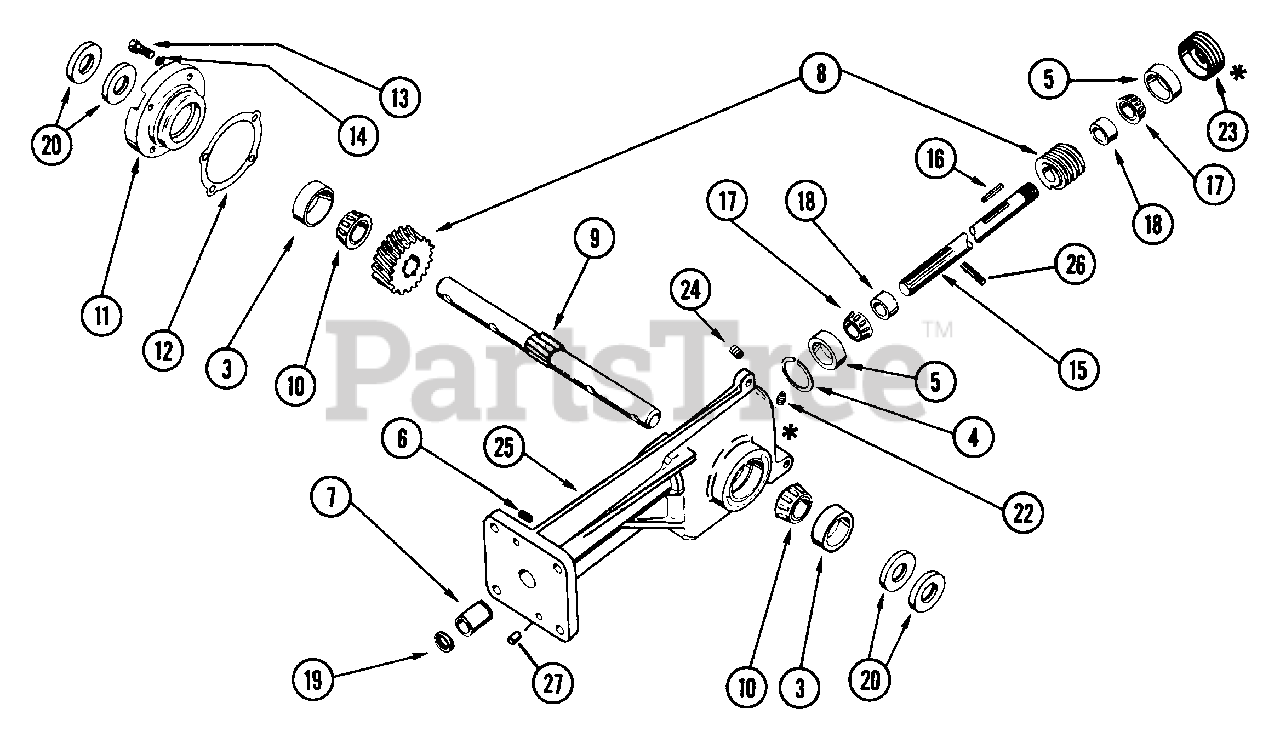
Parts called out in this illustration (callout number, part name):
1	TILLER GEARCASE - C.I.
3	BRG-CUP 2.328X.465
4	RG-RTNG-INT 1.781X.062
5	BRG-CUP 1.781X.475
6	BREATHER
7	BRG-NEEDLE .750X1.0X.62
8	WORM AND WORM GEAR ASSEMBLY
9	TINE SHAFT
10	BRG-CONE 1.25X.66
11	BEARING FLANGE
12	SERVICE KIT
13	BLT-HEX .38-16X1.00 PL GR5
14	WSHR-LK .375X.115 HVY PL
15	WORM SHAFT
16	KEY-SQ .188X1.0X.188 SAE 8630
17	BRG-CONE .750X.61
18	BSHG, SPCR .755X1.12X.50 PM
19	SEAL .750X1.000X.125
20	SEAL 1.250X2.00X.250
22	PIPE PLUG
23	ADJUSTMENT PLUG
24	SCR-SET .25-20X.25 SKHCUPNY OH
25	TILLER GEARCASE - C.I.
26	PIN-ROLL .125X1.00
27	PIN-GRV .375X1.00 TP C
